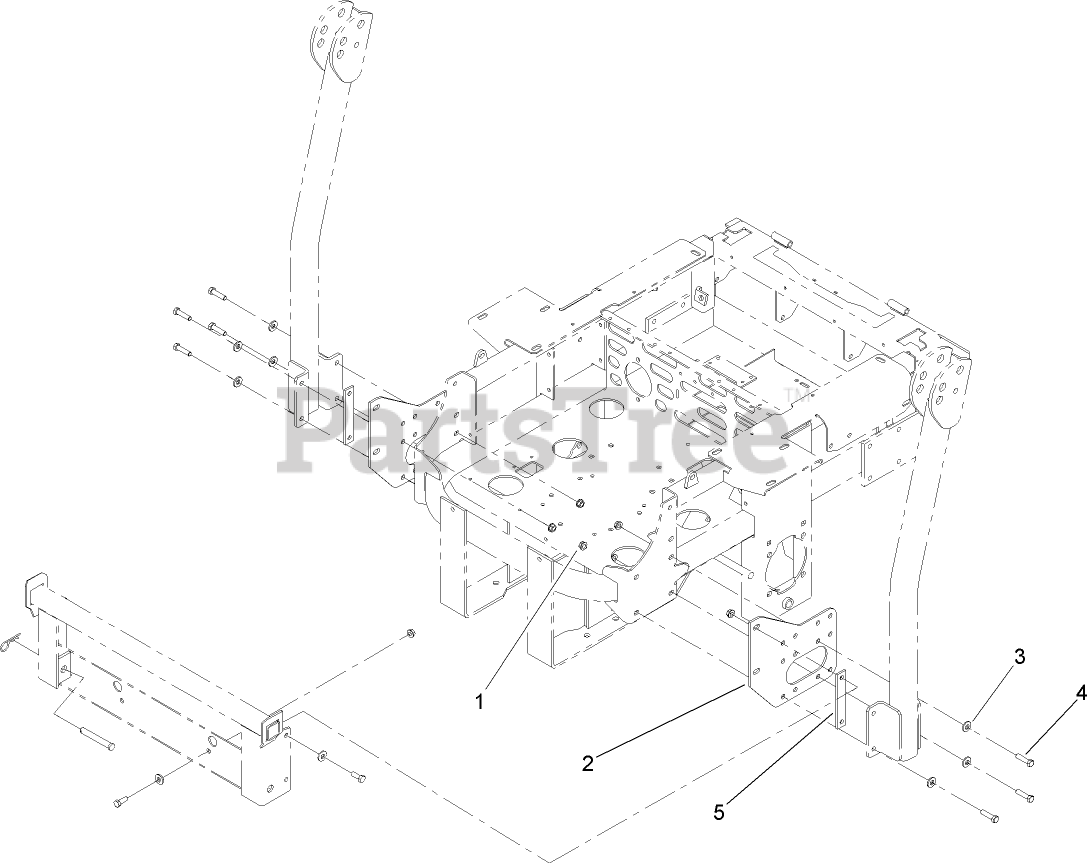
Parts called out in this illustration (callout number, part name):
1	NUT-HHF, WHIZ
2	PLATE-MOUNT, BAGGER
3	WASHER-BELLEVILLE
4	SCREW-HH
